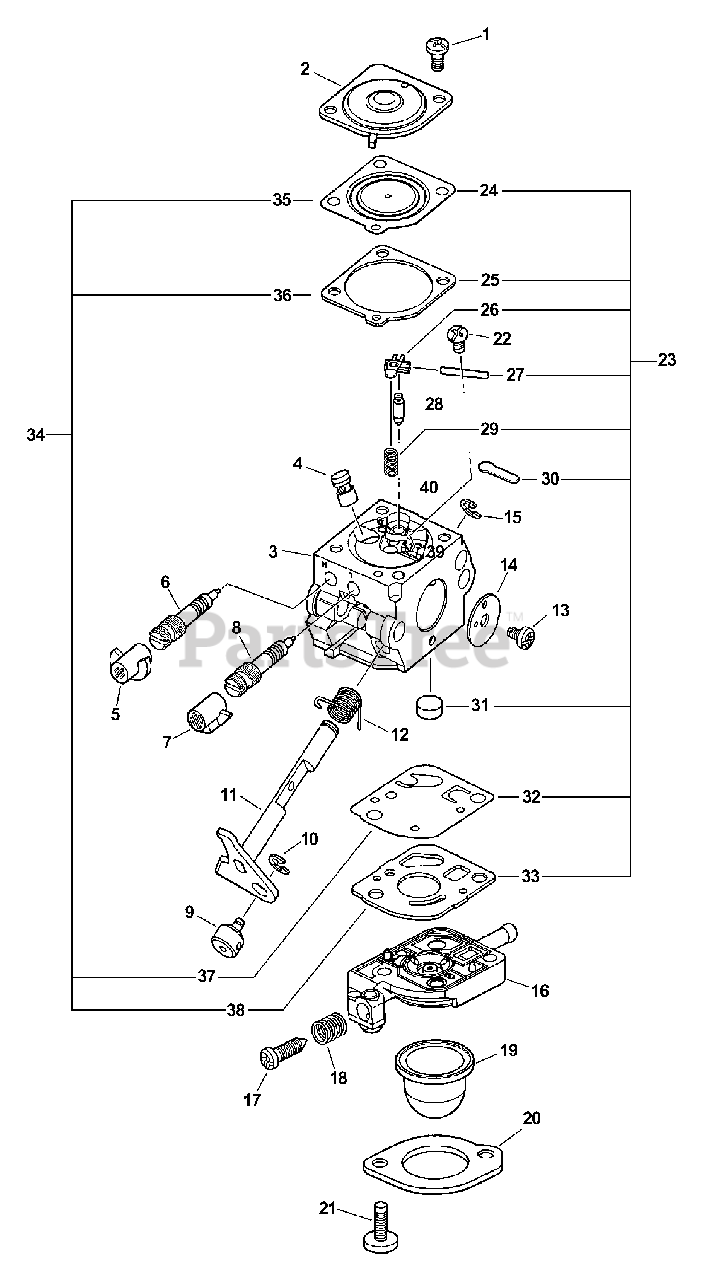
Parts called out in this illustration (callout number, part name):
2	COVER, METERING DIAPHRAGM
3	BODY, CARBURETOR
4	NOZZLE, CHECK VALVE
5	CAP, LIMITER - RED
6	NEEDLE, HIGH SPEED
7	CAP, LIMITER - WHITE
8	NEEDLE, MIXTURE
11	SHAFT, THROTTLE
12	SPRING, THROTTLE RETURN
14	VALVE, THROTTLE
16	BODY ASSY, PURGE
17	SCREW, THROTTLE ADJUST
18	SCREW, THROTTLE ADJUST
19	BULB, PURGE
20	RETAINER
23	REPAIR KIT, CARBURETOR
24	DIAPHRAGM, METERING
25	GASKET, METERING
26	LEVER, METERING
27	PIN, METERING LEVER
28	VALVE, INLET NEEDLE
29	SPRING, METERING LEVER
30	PLUG, WELCH
31	STRAINER
32	DIAPHRAGM, PUMP
33	GASKET, PUMP
34	GASKET / DIAPHRAGM KIT
35	DIAPHRAGM, METERING
36	GASKET, METERING
37	DIAPHRAGM, PUMP
38	GASKET, PUMP
